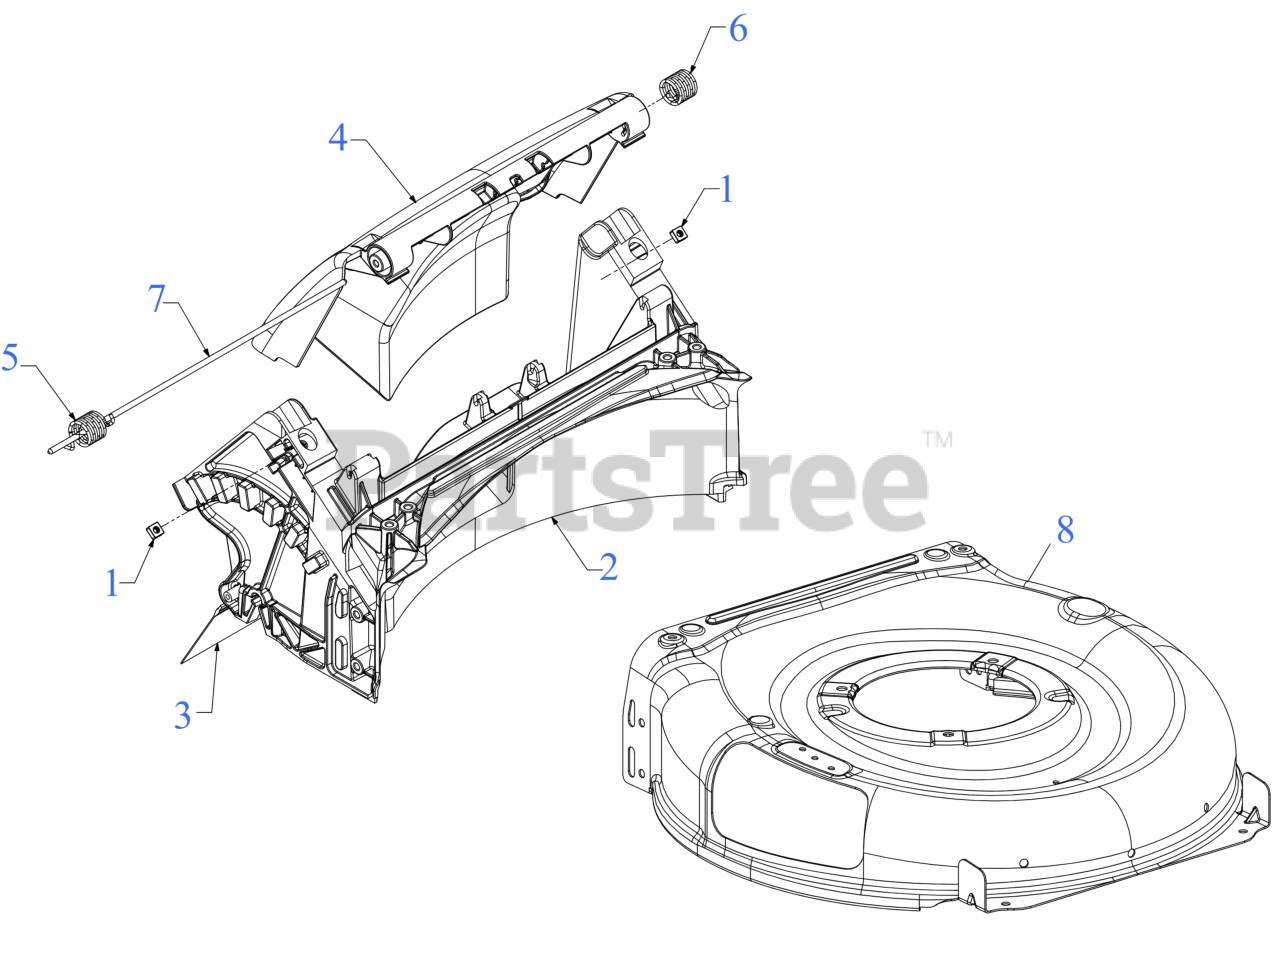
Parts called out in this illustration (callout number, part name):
1	SQUARE NUT 1/4-20
2	REAR DOOR & BAFFLE ASSEMBLY
3	TRAILSHIELD
4	REAR DOOR & BAFFLE ASSEMBLY
5	TORSION SPRING (RH)
6	TORSION SPRING (LH)
7	REAR DOOR PIVOT ROD
